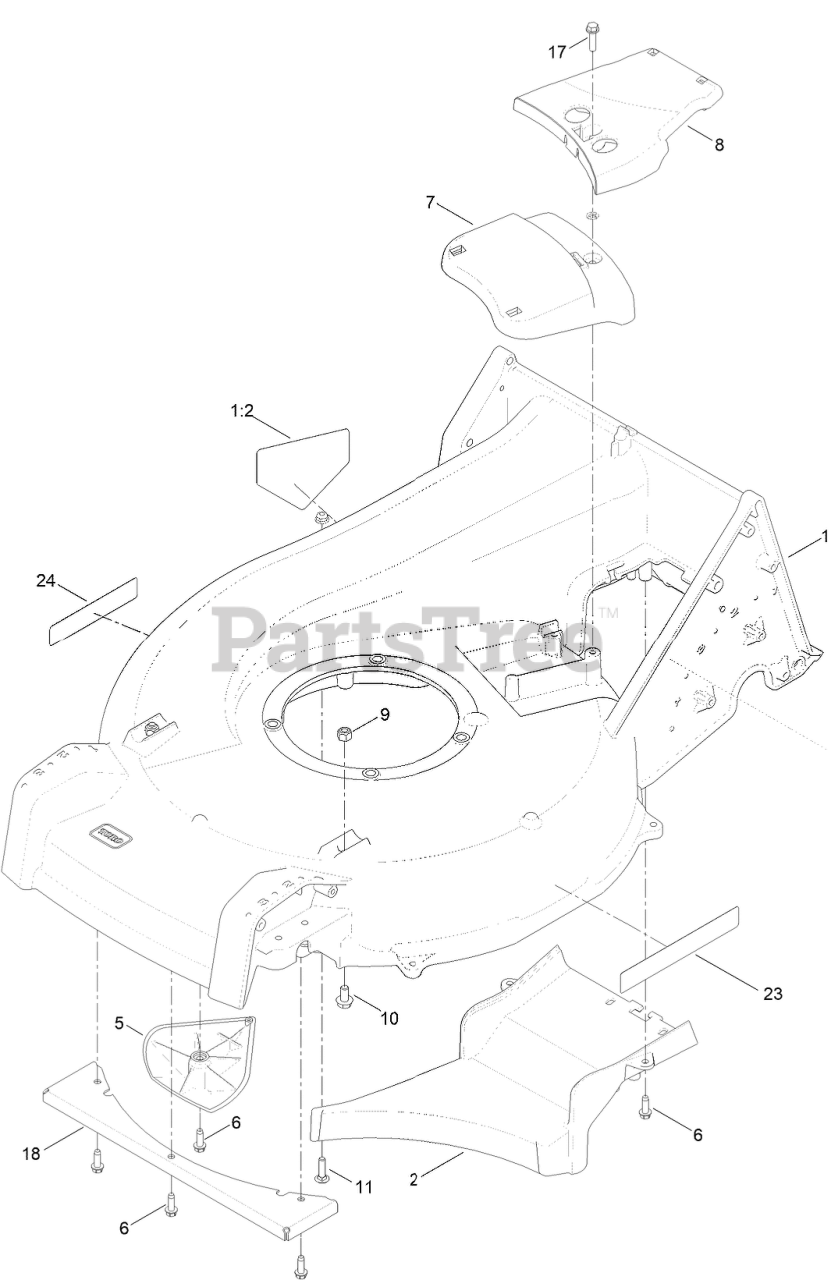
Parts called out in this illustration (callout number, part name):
1	HOUSING ASM
1:2	DECAL-DANGER
2	FLOOR-CHUTE
5	KICKER
6	SCREW-HWHTF
7	COVER-BELT, FRONT
8	COVER-BELT, REAR
9	GUARD-ENGINE
10	NUT-HF, NI
11	SCREW-CARR
17	SCREW-HWHTF
18	GUARD-TOE, FRONT
23	DECAL-RECYCLER
